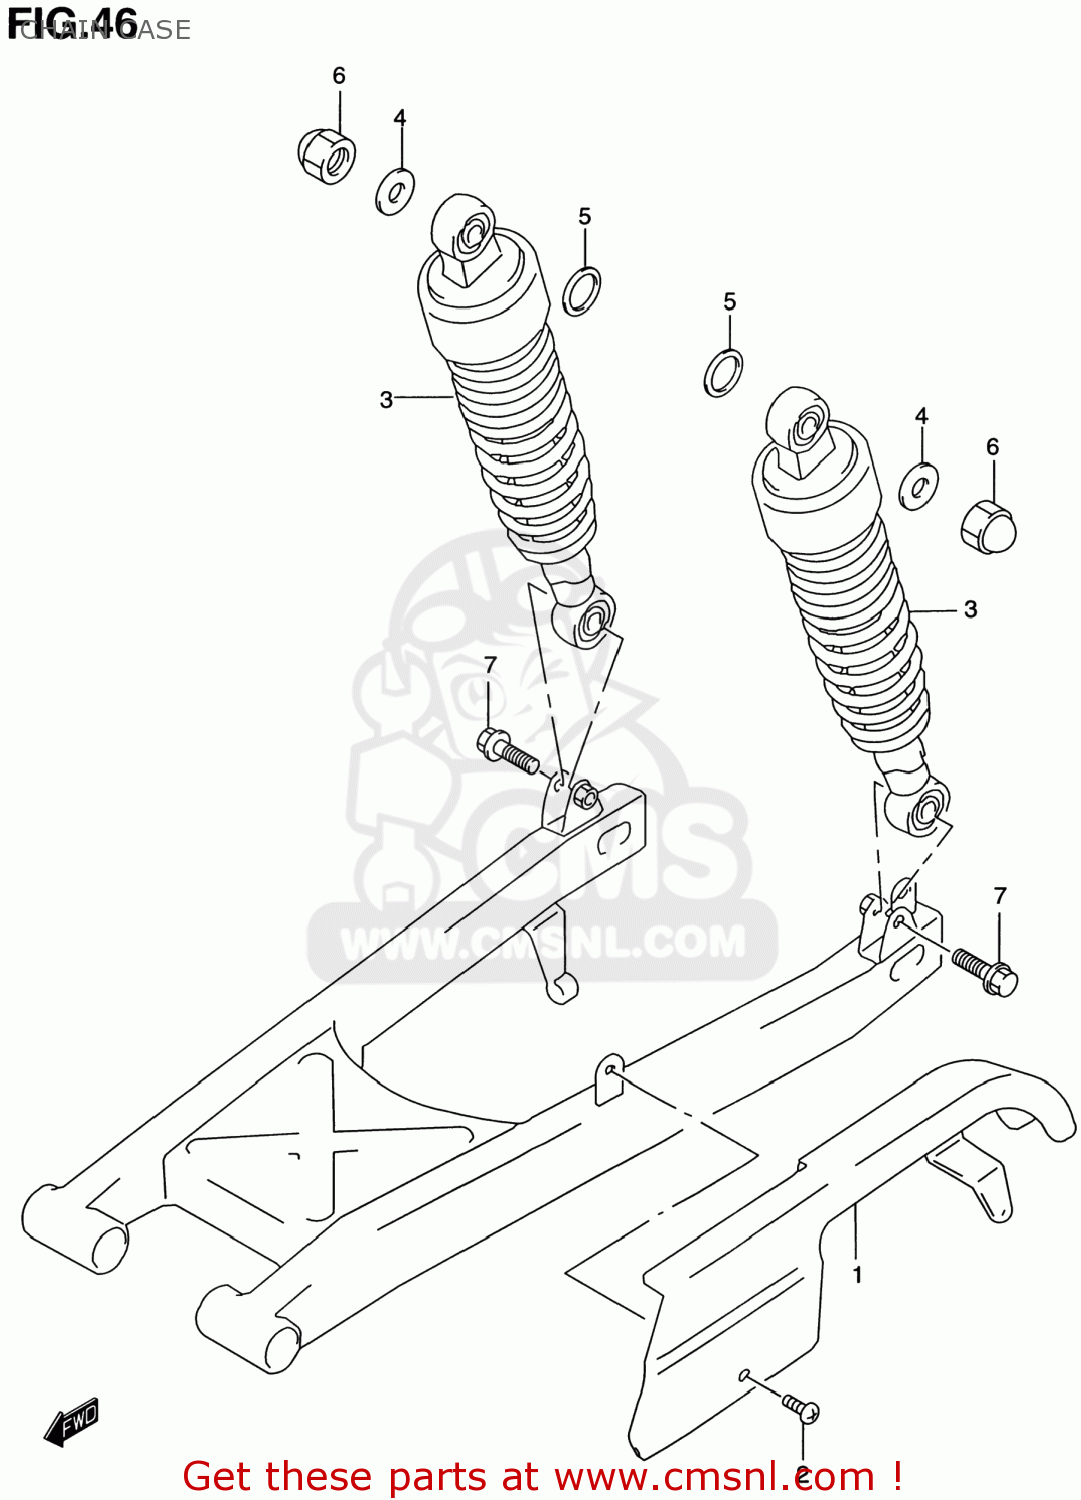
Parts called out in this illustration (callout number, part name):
1	CASE,CHAIN
2	SCREW
3	ABSORBER ASSY,RR SHOCK
4	WASHER (10.5X24X2.3)
5	WASHER
6	NUT
7	BOLT(10X37)
